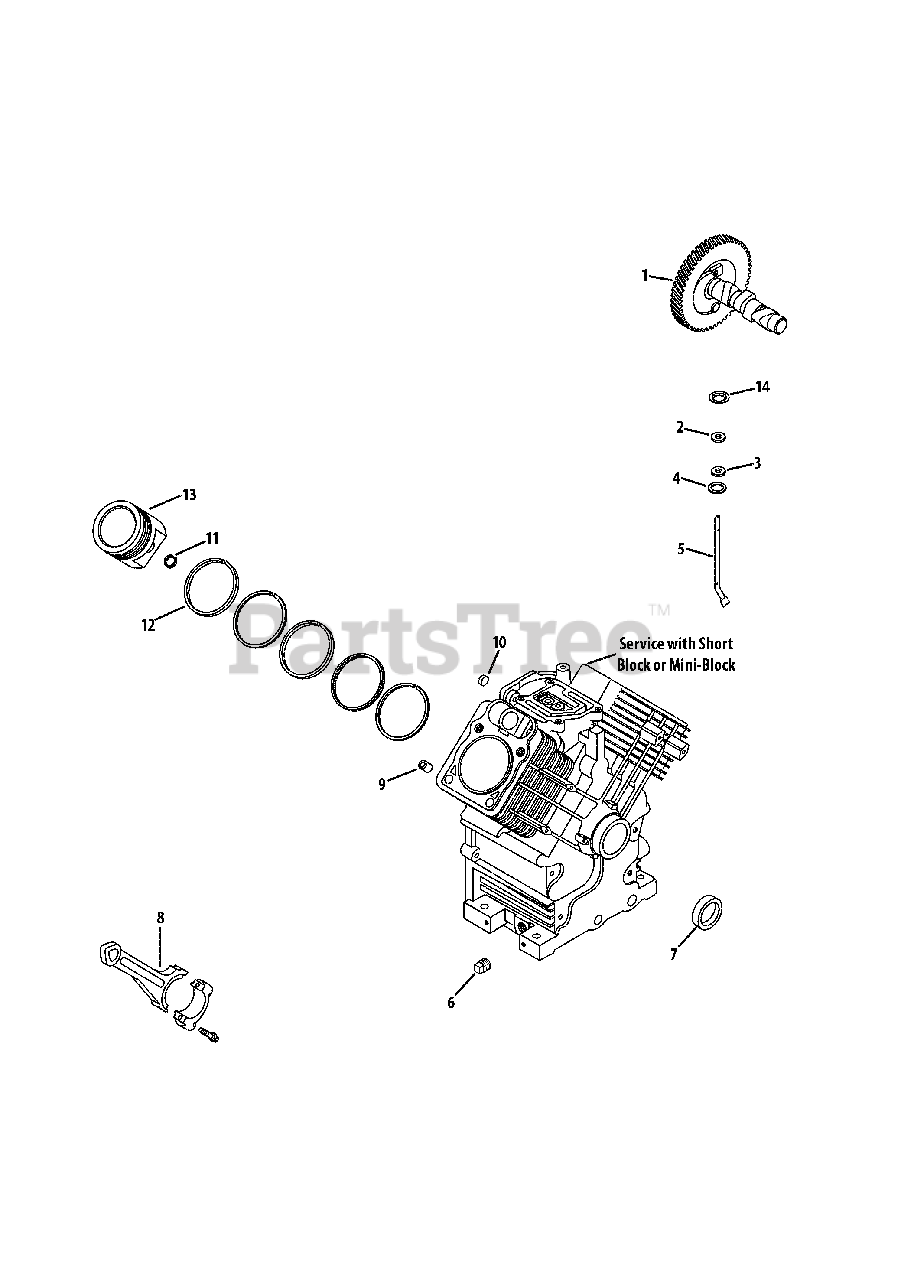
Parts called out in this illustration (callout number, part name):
1	Camshaft Kit
2	Flat Washer, 9 MM
3	Governor Cross Shaft Seal
4	Flat Washer, 11/32
5	Governor Cross Shaft
6	Square Head Pipe Plug, 3/8
7	Oil Seal (Helix Lip)
8	Connecting Rod Assembly
11	Piston Pin Retainer
12	Ring Set (Std)
12	Ring Set (.08)
12	Ring Set (.25)
12	Ring Set (.50)
13	Piston Assembly Kit w/ Ring (Std.) 77MM
13	Piston Assembly Kit w/ Ring Set (.08) 77MM
13	Piston Assembly Kit w/Ring Set (.25) 77MM
13	Piston Assembly Kit w/ Ring Set (.5) 77MM
14	Ring Retainer
